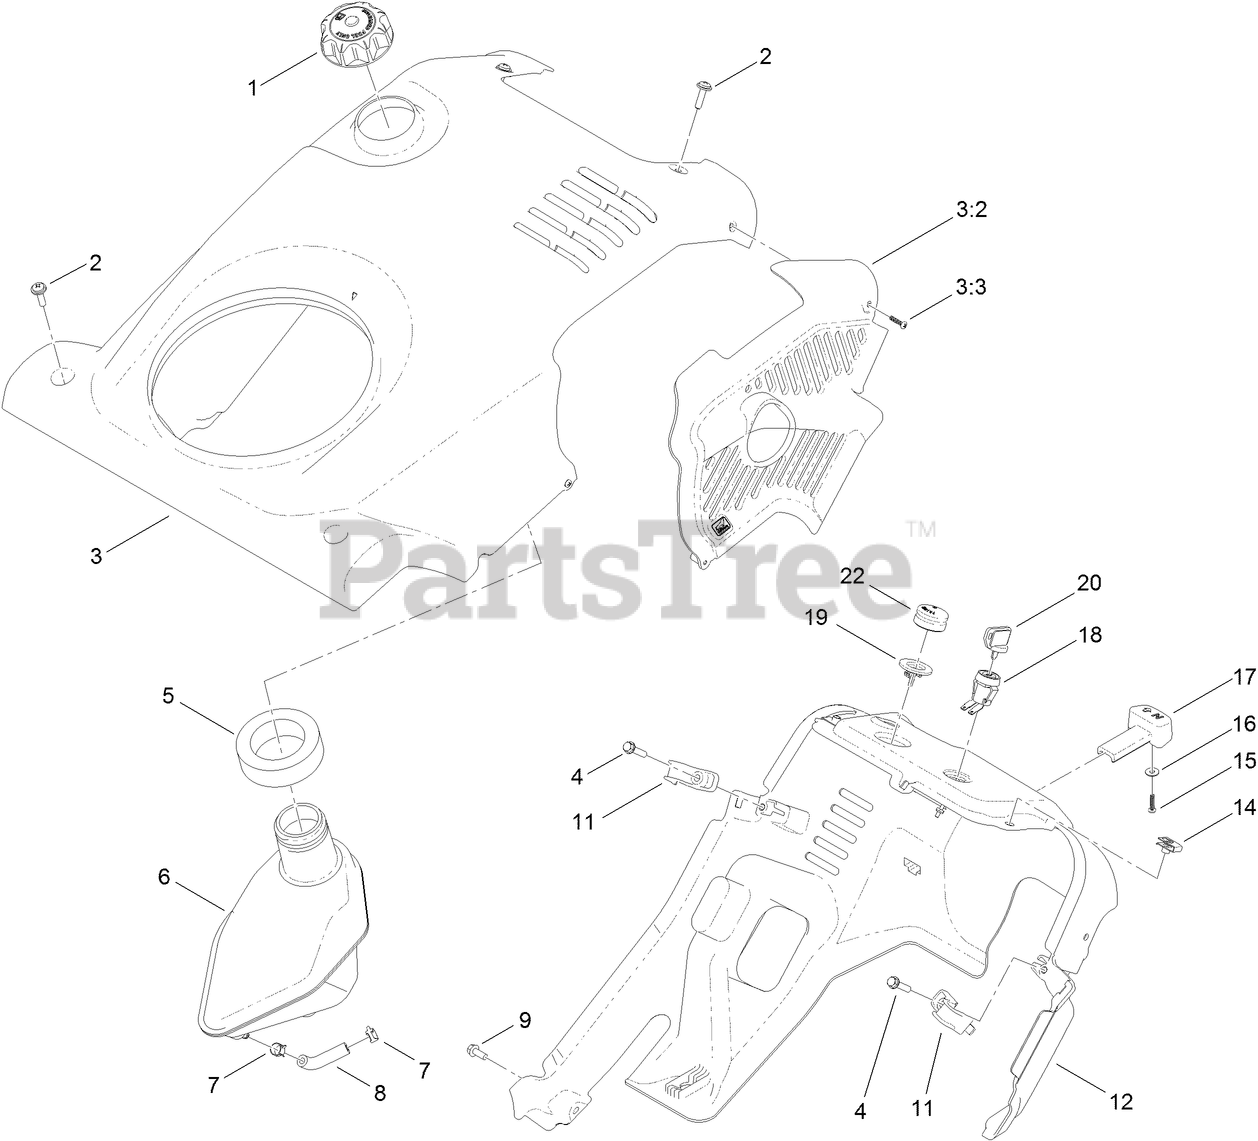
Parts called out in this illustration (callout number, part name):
2	SCREW-PPH
3	SHROUD ASM
3:2	BAFFLE-EXHAUST
3:3	SCREW-PPH
4	SCREW-PLASTITE
5	SEAL-TANK
6	TANK-FUEL, GAS
7	CLAMP-HOSE
8	HOSE-FUEL
9	SCREW-HWH
11	CLIP-SHROUD
12	SHROUD-LOWER
15	SCREW-PPH
16	WASHER-PLAIN
17	KNOB-CHOKE
18	SWITCH
19	BODY-PRIMER
20	KEY-IGNITION
22	BULB-PRIMER
